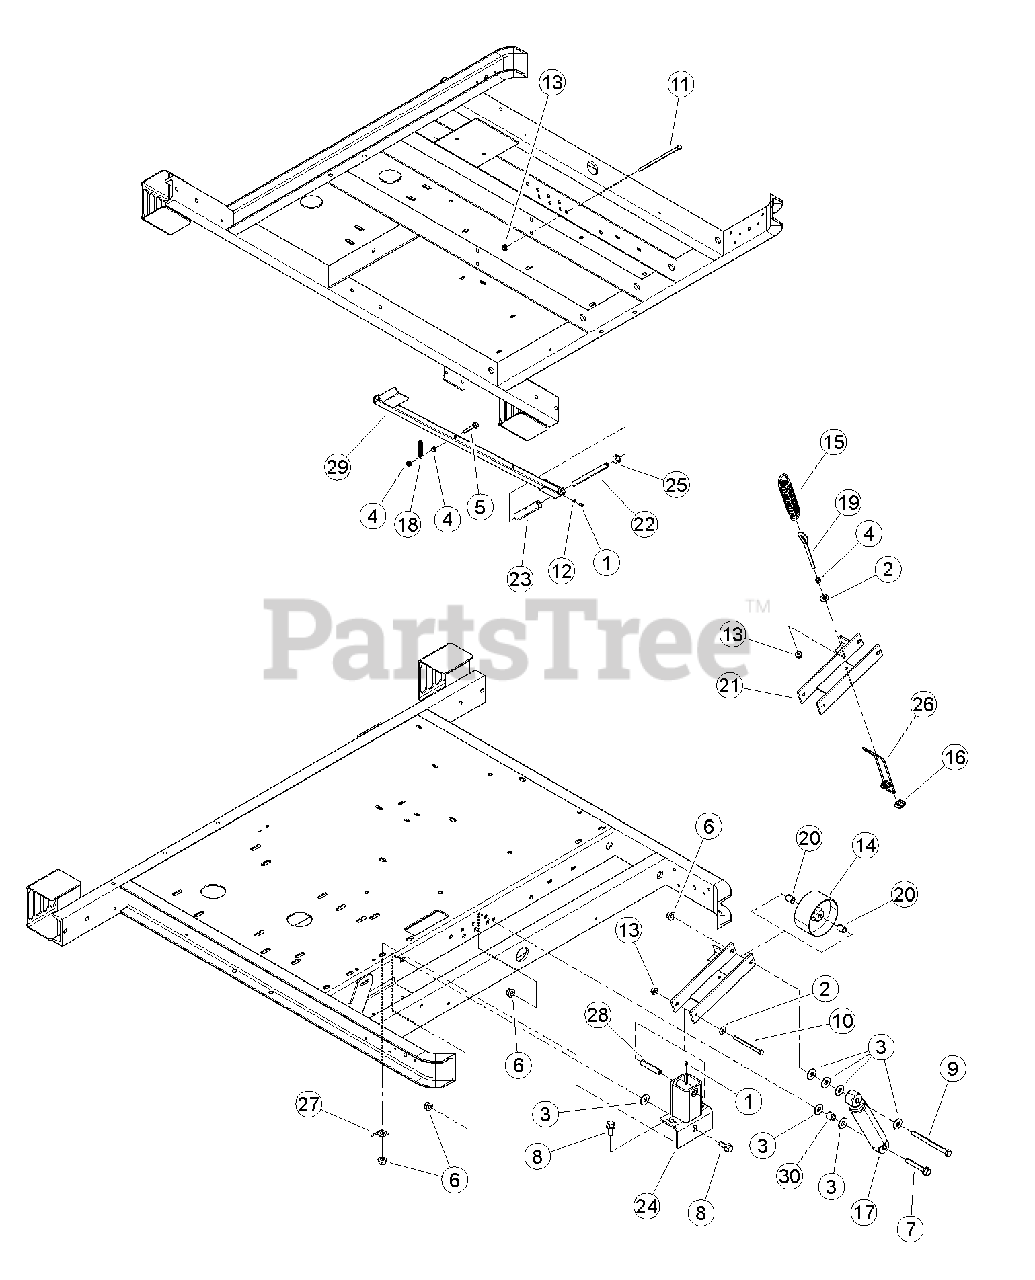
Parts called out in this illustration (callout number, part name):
1	FITTING, 1/4 SELF-TAP GREASE
2	WASHER, 3/8" FLAT ZP
3	WASHER, 1/2" FLAT ZP
4	NUT, 3/8" HEX NC ZP
5	BOLT, 3/8 X 2 FLANGE NC
6	NUT, 1/2-13 NYLOCK FLANGE
7	BOLT, 1/2-13 X 3-1/4 HWH GR8 YZP
8	BOLT, 1/2 -13 X 1-1/4 FLANGE NC
9	BOLT, 1/2 X 6 G5 HCS ZP
10	BOLT, 3/8 X 4-1/2" HHCS GR5 NC ZP
11	BOLT, 3/8 X 7-1/2" HHCS GR5 NC ZP
12	WASHER, FLAT .254 X .400 X .048
13	NUT, 3/8-16 NYLOCK FLANGE
14	PULLEY, IDLER 5 X 2.50"
15	SPRING, 7-3/4" EXTENSION
16	CLAMP, 3/16 CABLE
17	ABSORBER, IDLER SHOCK
18	SPRING, LT EXT .555 OD X 2.75 LG
19	EYEBOLT, 3/8 X 5" LG 4-1/4 THD ZP
20	SPACER, .75 X .90
21	WELDMENT, IDLER ARM
22	SPACER, .63 X 6.44
23	SPACER, 1.0 X 4.25
24	WELDMENT, IDLER SUPPORT
25	SPACER, 1.0 X 0.50
26	CABLE, 3/16 X 24-1/2
27	ANGLE, SPRING ANCHOR
28	SPACER, .63 X 3.06
29	WELDMENT, CHIPPER CLUTCH PEDAL
30	SPACER, 7/8 X 3/4
